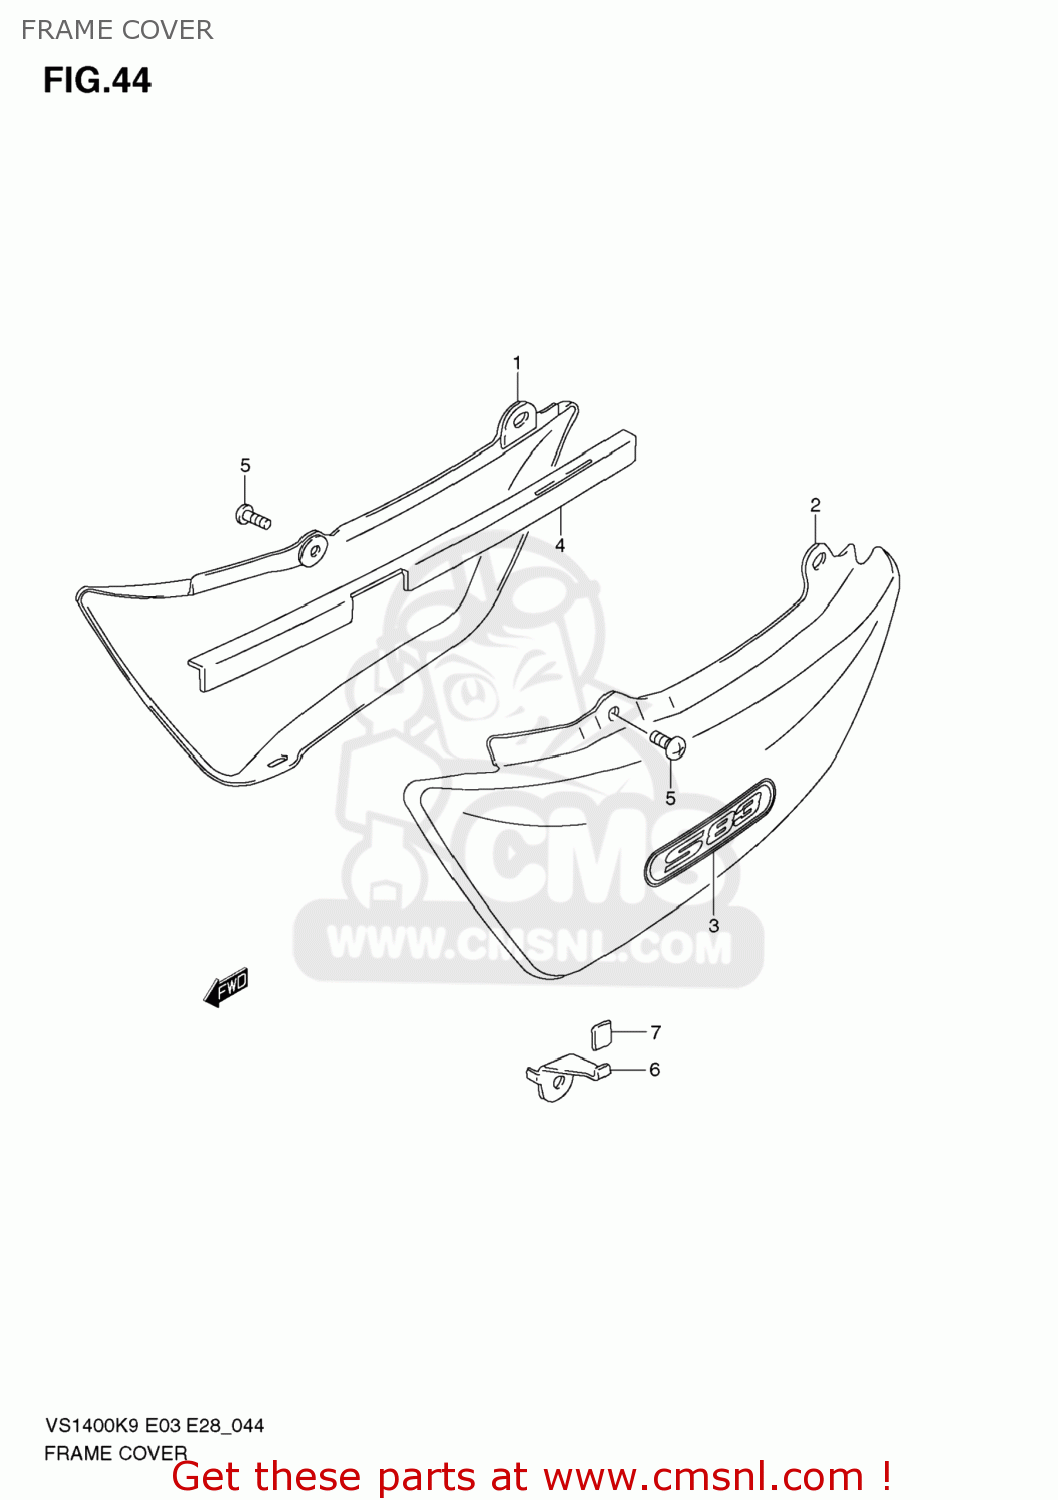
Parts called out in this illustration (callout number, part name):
1	COVER,FRAME,R(GRAY)
2	COVER,FRAME,L(GRAY)
3	EMBLEM,FRAME COVER
4	PROTECTOR,FRAME COVER,R
5	SCREW
6	HOOK,FRAME COVER,L
7	CUSHION,FRAME COVER HOOK
